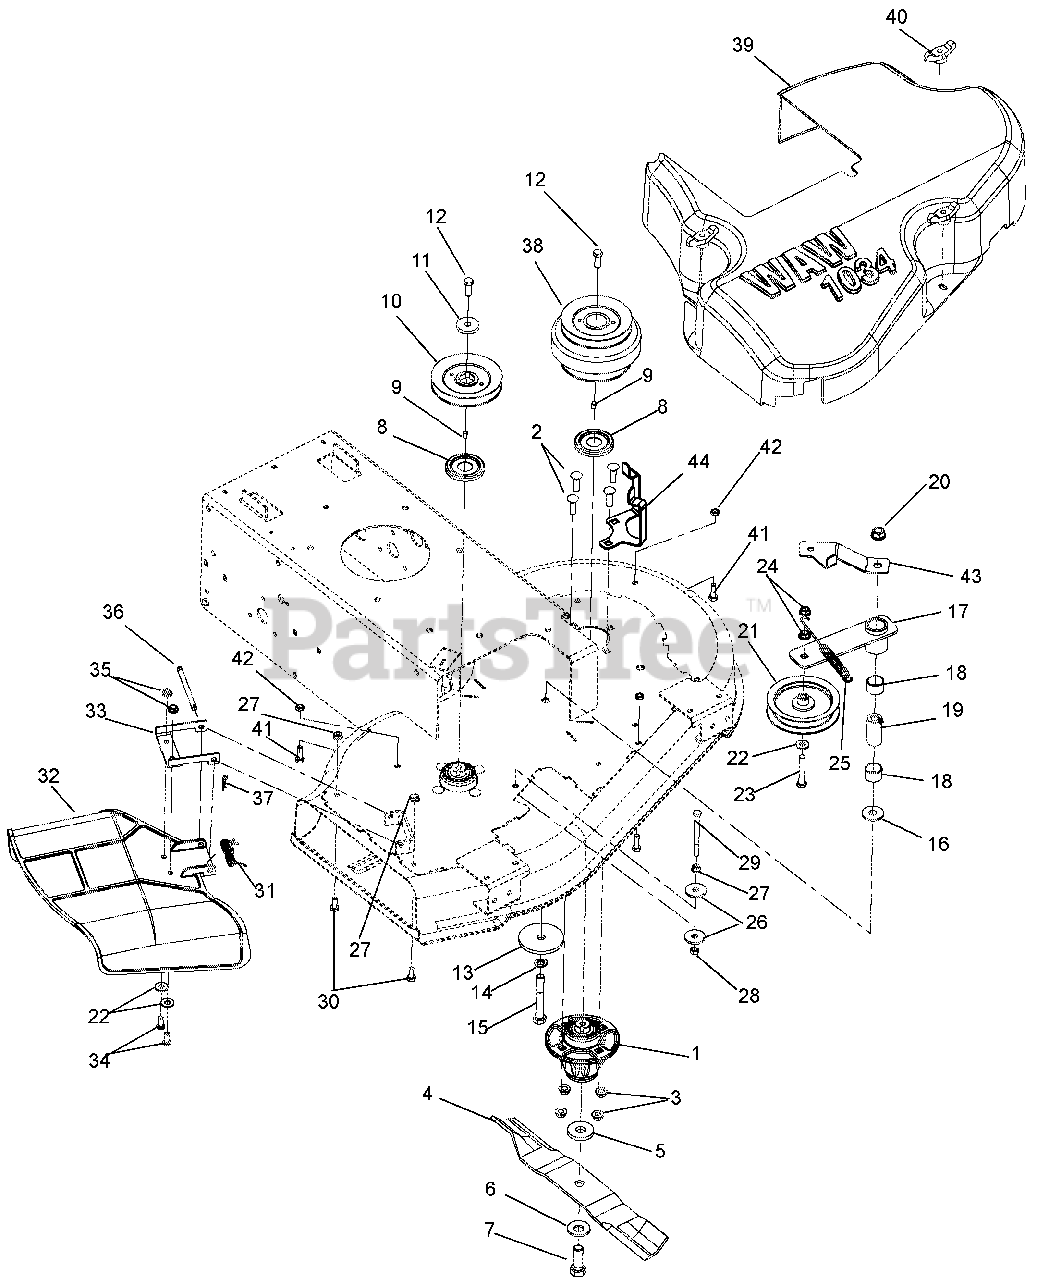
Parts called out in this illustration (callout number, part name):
1	SPINDLE ASSEMBLY
2	@BLT-RDHDSQNK .38-16X1.25 G5YZ
3	@NUT-LK-NYL-FLG .38-16 YWZC
4	BLADE, 17.38X2.5X.204
5	WSHR-FLT .640X1.75X.250 YWZC
6	WSHR-BLVL .669X1.535X.138
7	BLT-HEX .62-18X1.75 GR8 YWZC
8	DUST CAP
9	KEY, SQ .25 X .38 X .25
10	SHEAVE, 4.75 DIA A-SECTION
11	WSHR,FLT STL.406X1.50X.245YWZC
12	BLT-HEX .38-16X1.0 GR8 YZ EP30
13	WASHER, FLAT .531X3.000X.25
14	@WSHR-LK .50X.125 REG YWZC
15	@BLT-HEX .50-13X3.50 GR5 YWZC
16	WSHR-FL-STL.511X1.441X.125 YWZ
17	ARM, WAW DECK IDLER (WLDMNT)
18	BRG, 1.00 X 1.12 X .75
19	BSHG, SPCR .502X.997X2.03 PM
20	@NUT-LK-TOP-FLG .50-13 YWZC
21	ASM, IDLER 4"
22	@WSHR-FL-STL.38X.875X.083 YWZC
23	@BLT-HEX .38-16X2.25 GR5 YWZC
24	NUT-LK-CTR-FLG .38-16 YWZC
25	SPRING - ENGINE - TRANS.
26	WSHR-FL-STL .406X1.375X.135 YZ
27	@NUT-SPNLK-FLG .312-18 YWZC
28	@NUT-LK-CTR .31-18 YWZC
29	@BLT-HEX .31-18X3.50 GR5 YWZC
30	@BLT-HEX .31-18X.75 GR5 YWZC
31	SPRING, TORSION
32	MOLDED CHUTE, ZOOM
33	CHUTE REINFORCEMENT
34	SCR-SKH .31-18X.75 BTNHD YWZC
35	@NUT-LK-TOP-FLG .31-18 YWZC
36	PIN, 5/16 X 3.88"
37	PIN-HAIR INT .08X.18X1.18 YWZC
38	PULLEY, WAW DECK INPUT
39	COVER, WAW BELT
40	KNOB - WING .312-18 UNC
41	@BLT-HEX .31-18X1.00 GR5 YWZC
42	@NUT-LK-CTR-JAM .31-18 YWZC
43	BRKT-IDLER BRACE
44	FINGER, JACKSHAFT BELT
